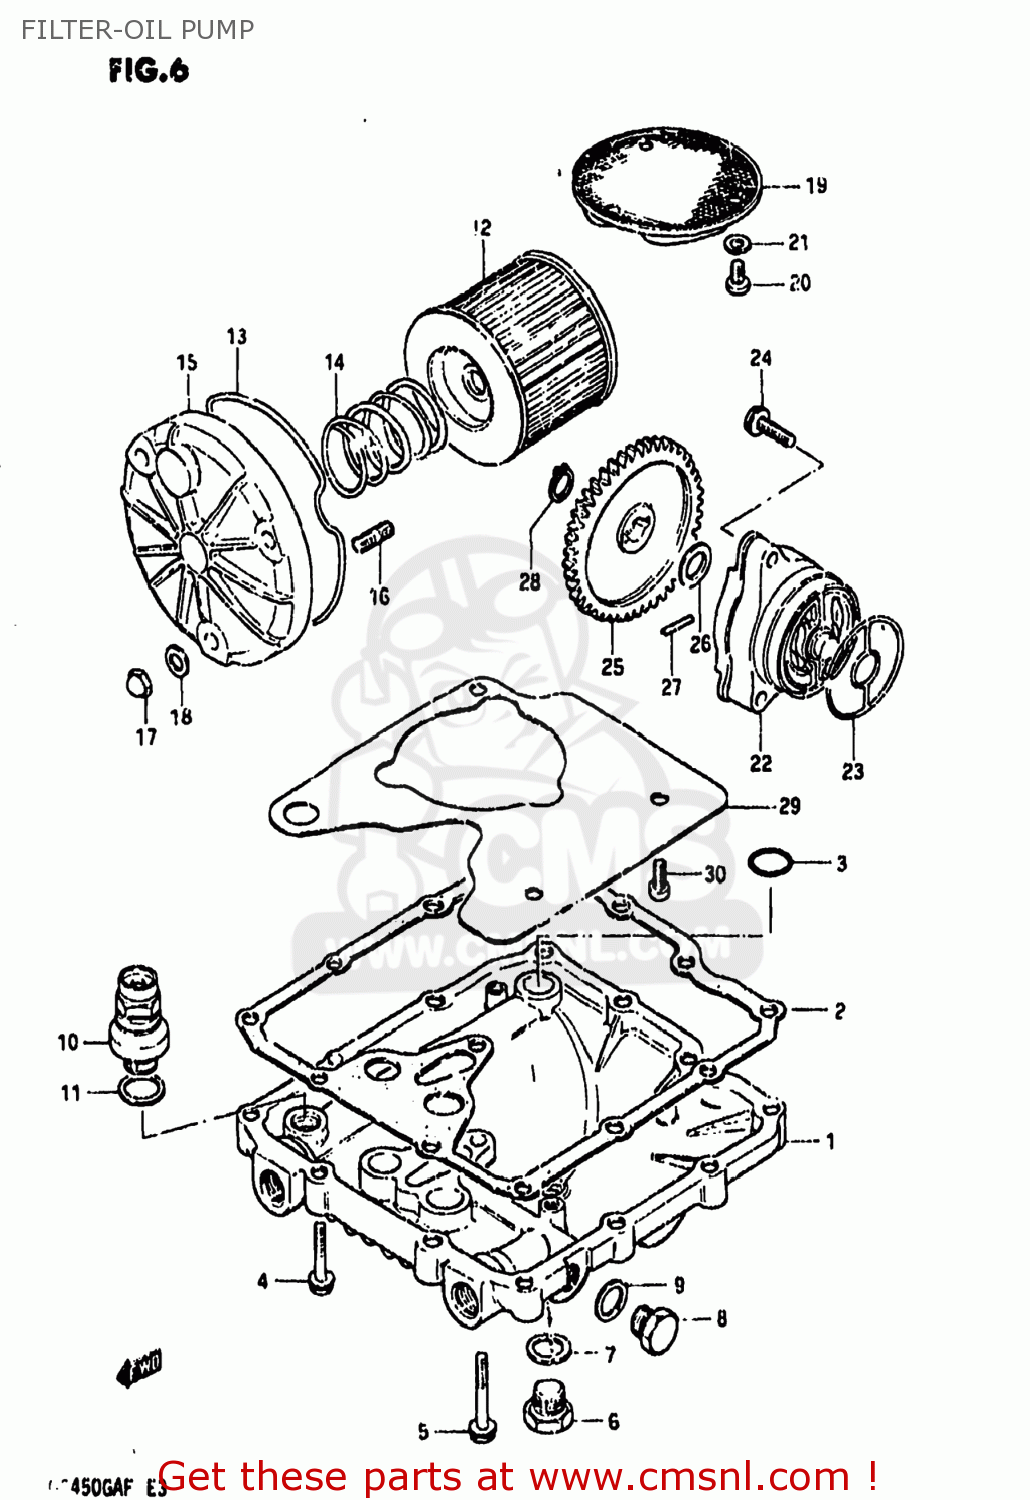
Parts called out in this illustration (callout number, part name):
1	PAN,OIL
2	GASKET,OIL PAN (MCA)
3	O RING(D:3.2,ID:12.9)
4	BOLT 6X30
5	BOLT 6X35
6	PLUG
7	GASKET(14X19.2X2) (NAS)
8	PLUG(12X9)
9	GASKET(12.1X16.2X3.7) (NAS)
10	REGULATOR ASSY,ENGINE OIL
11	WASHER
12	FILTER ASSY,ENGINE OIL
13	O RING,OIL FILTER CHAMBER CAP
14	SPRING
15	CAP,OIL FILTER
16	STUD 6X20
17	NUT 6MM
18	WASHER
19	STRAINER,ENGINE OIL
20	SCREW 6X12
21	LOCK WASHER
22	PUMP ASSEMBLY,OIL
23	O RING,OIL PUMP
24	BOLT(6X32)
25	GEAR,OIL PUMP DRIVEN
26	SHIM
27	PIN(4X15.8)
28	CIRCLIP
30	SCREW 6X12
